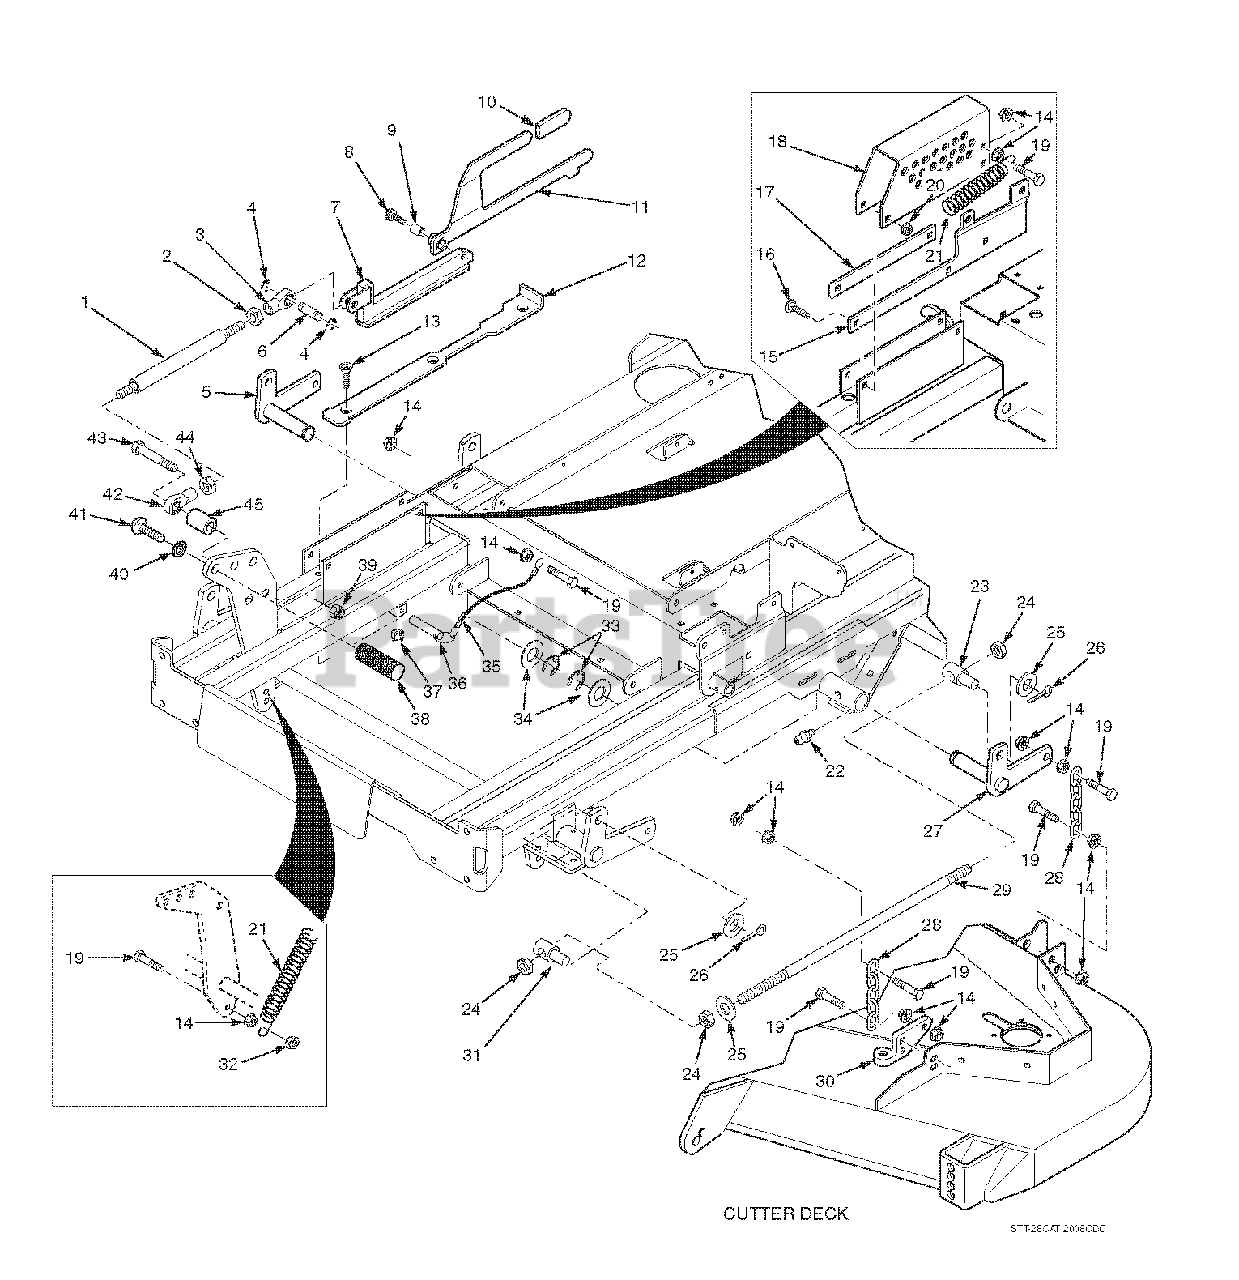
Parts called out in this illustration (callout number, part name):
1	Link, Deck Lift
2	Nut, Jam 1/2-20 LH
3	Rod End, Female - 1/2-20 LH
4	Ring, Retaining 1/2" External "E"
5	Bellcrank Weldment, RH Rear
6	Pin, Decklift
7	Slide Weldment, Height Adjustment
8	Bolt, Shoulder 1/2 x 3/4"
9	Bushing, .502 ID.
10	Grip, Deck Latch
11	Deck Latch
12	Lockplate, Decklift
13	Screw, Cap 5/16-18 x 3" FHHS
14	Nut, Hex Serrated Flange 3/8-16
15	Guide, Long
16	Bolt, Carriage 5/16-18 x 1"
17	Guide, Short
18	Bracket, Cutting Height Adjustment
19	Bolt, Hex Head 3/8-16 x 1-1/2"
20	Nut, Hex Serrated Flange 5/16-18
21	Spring, Helper
22	Grease Fitting
23	Swivel Joint, LH
24	Nut, Hex 5/8-11
25	Flatwasher, 5/8" (.656 x 1.312 x .095)
26	Cotter Pin, 3/16 x 1"
27	Bellcrank Weldment, LH Rear
28	Chain
29	Stud, 5/8-11 x 26.0"
30	Lever Assembly, Deck Level
31	Swivel Joint, RH
32	Locknut, 3/8-16 Center Lock
33	Ring, Retaining 1" External "E"
34	Flatwasher, 1" (1.062 x 1.50 x .048)
35	Lanyard, Deck Height Pin
36	Ring Pin, 1/2 x 3.06"
37	Nut, 3/8-16 Elastic Stop
38	Foot Pedal, Height Adjustment
39	Nut, Hex Elastic Stop 1/2-13
40	Lockwasher, 5/8"
41	Capscrew, 5/8-11 x 1-1/2"
42	Rod End, Female - 1/2-20 RH
43	Bolt, Hex Head 1/2-13 x 3"
44	Nut, Jam 1/2-20 RH
45	Spacer, Decklift Pedal
